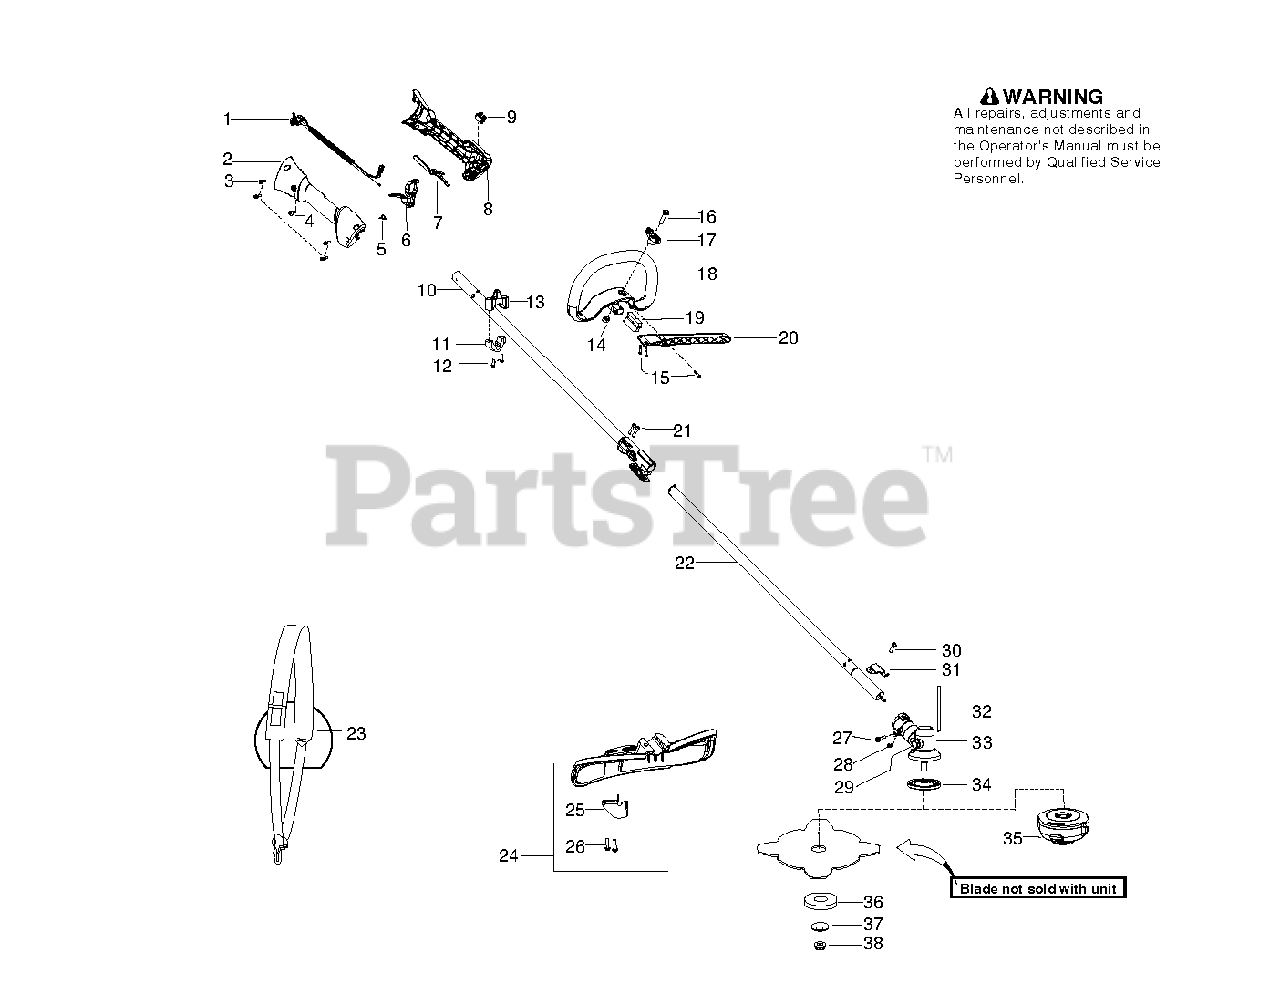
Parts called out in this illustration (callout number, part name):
1	ASSY CABLE / WIRE HARNESS
2	HOUSING RIGHT
3	SCREW M4 X 1.75 PT 16MM
4	SCREW-10-16 X 1/2, TYPE 2
5	SPRING TRIGGER
6	TRIGGER
7	THROTTLE LOCKOUT
8	HOUSING THROTTLE LH
9	SWITCH
10	KIT DRIVESHAFT UPPER
11	CLAMP HARNESS LOWER
13	CLAMP HARNESS UPPER
15	SCREW IHSCFTO
16	SCREW M6X50
20	HANDLE
22	KIT DRIVESHAFT LOWER LDX
23	STRAP
24	KIT SHIELD
25	LINE CUTTER
27	SCREW - CARB. ADAPTOR
29	PLUG
30	SCREW 1/4-20 X 7/8 (TAP
31	BRACKET SHIELD STRAIGHT SHAFT
32	LOCKING PIN
33	ASSY GEARBOX
34	DRIVE DISC
35	T25 TRIM HEAD 10MM LH
36	SUPPORTING CUP
37	SUPPORT FLANGE
38	GEARHEAD NUT - BRUSHCUTTER
